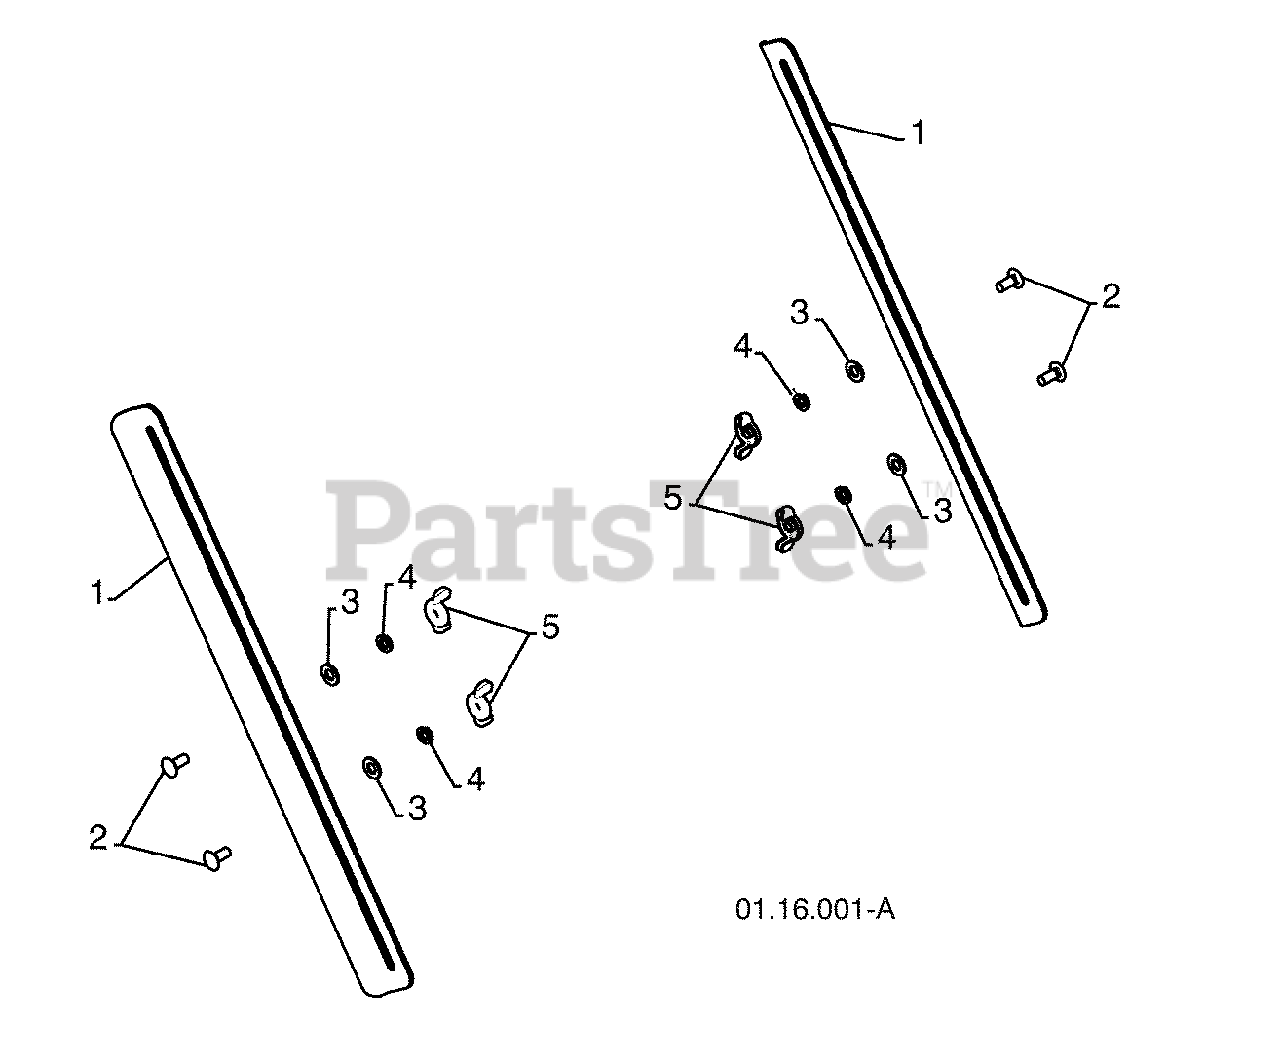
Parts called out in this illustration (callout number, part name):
1	DRIFT CUTTER BAR
2	CARRIAGE BOLT 5/16-18 X .750
3	PLASTIC WASHER
4	LOCKWASHER 5/16
5	NUT 5/16-18
